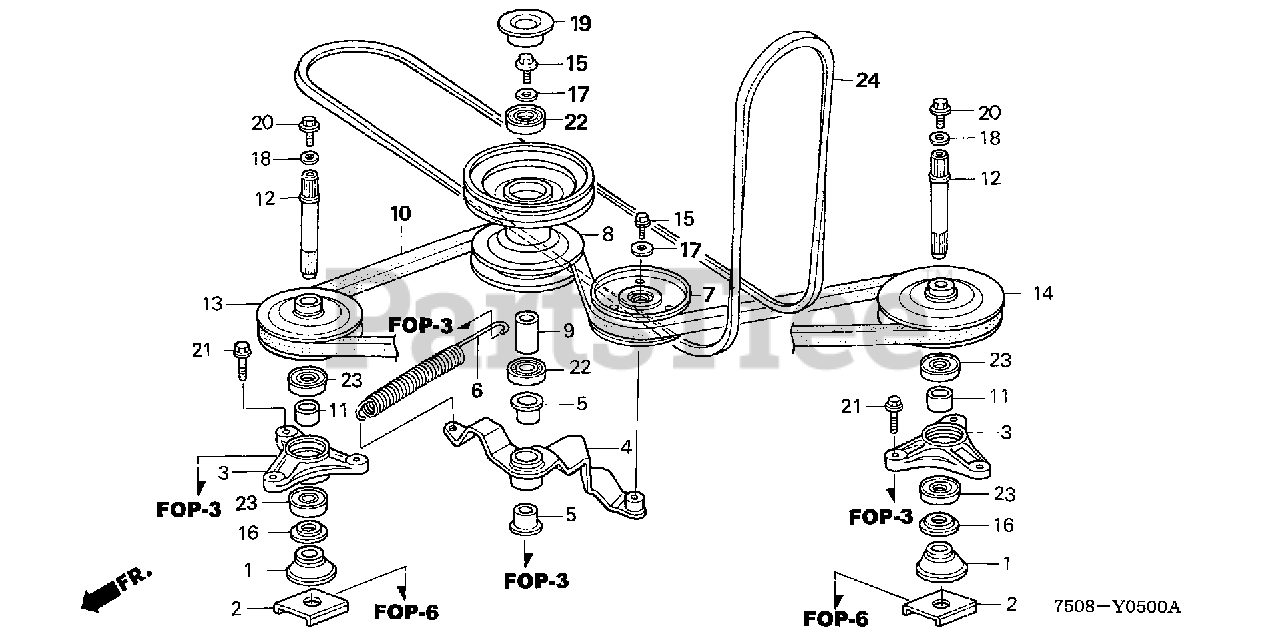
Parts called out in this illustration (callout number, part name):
1	HOLDER, BLADE
2	HOLDER, BLADE (B)
3	HOUSING, BEARING (NOT AVAILABLE)
4	ARM, TENSIONER
5	BUSH, TENSIONER ARM
6	SPRING, TENSIONER ARM
7	ROLLER, TENSIONER
8	PULLEY KIT, DRIVEN
8	PULLEY, DRIVEN
9	COLLAR, DRIVEN PULLEY
10	V-BELT, BLADE (LB-60)
11	COLLAR, BLADE SHAFT
12	SHAFT, BLADE
13	PULLEY, BLADE (115)
14	PULLEY, BLADE (109)
15	BOLT, WHEEL
16	WASHER, BLADE HOLDER
17	WASHER (8MM)
18	WASHER (10.3MM)
19	PLUG, SEALING (40X6)
20	BOLT, FLANGE (10X16)
21	BOLT, FLANGE (10X28)
22	BEARING, RADIAL BALL (6203UU)
23	BEARING, RADIAL BALL (6204UU)
24	V-BELT, DECK
